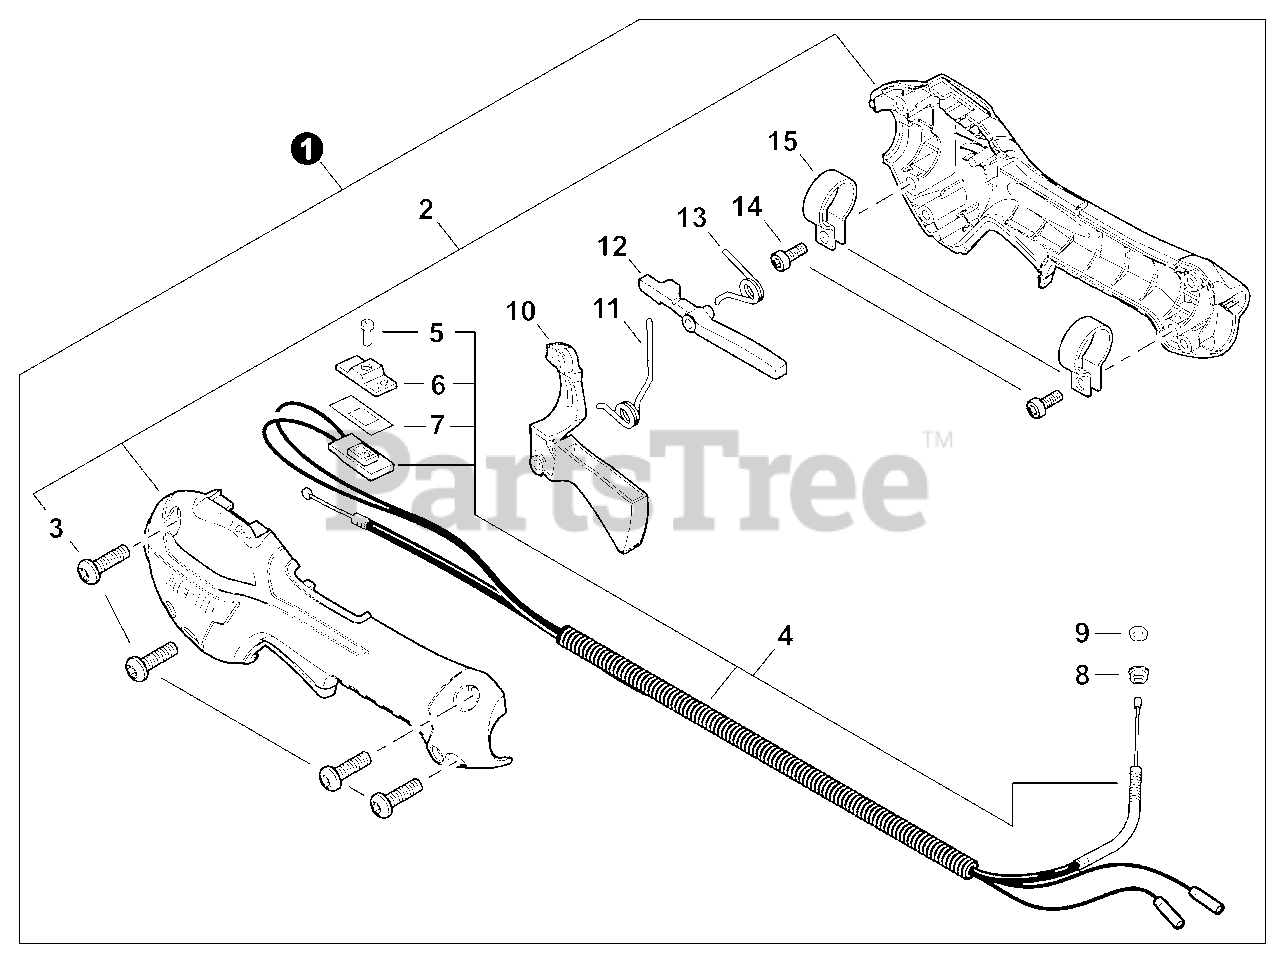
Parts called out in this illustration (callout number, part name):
1	CONTROL HANDLE ASSY
2	CONTROL HANDLE KIT
3	BOLT, TORX 5×16
4	CABLE ASSY, CONTROL
5	SCREW 3×10
6	KNOB, SWITCH - ORANGE
7	SEAL, SWITCH
8	NUT, FLANGE M6
10	TRIGGER, THROTTLE
11	SPRING, TORSION
12	LEVER, THROTTLE LOCKOUT
13	SPRING, TORSION
14	BOLT, TORX 5×16
